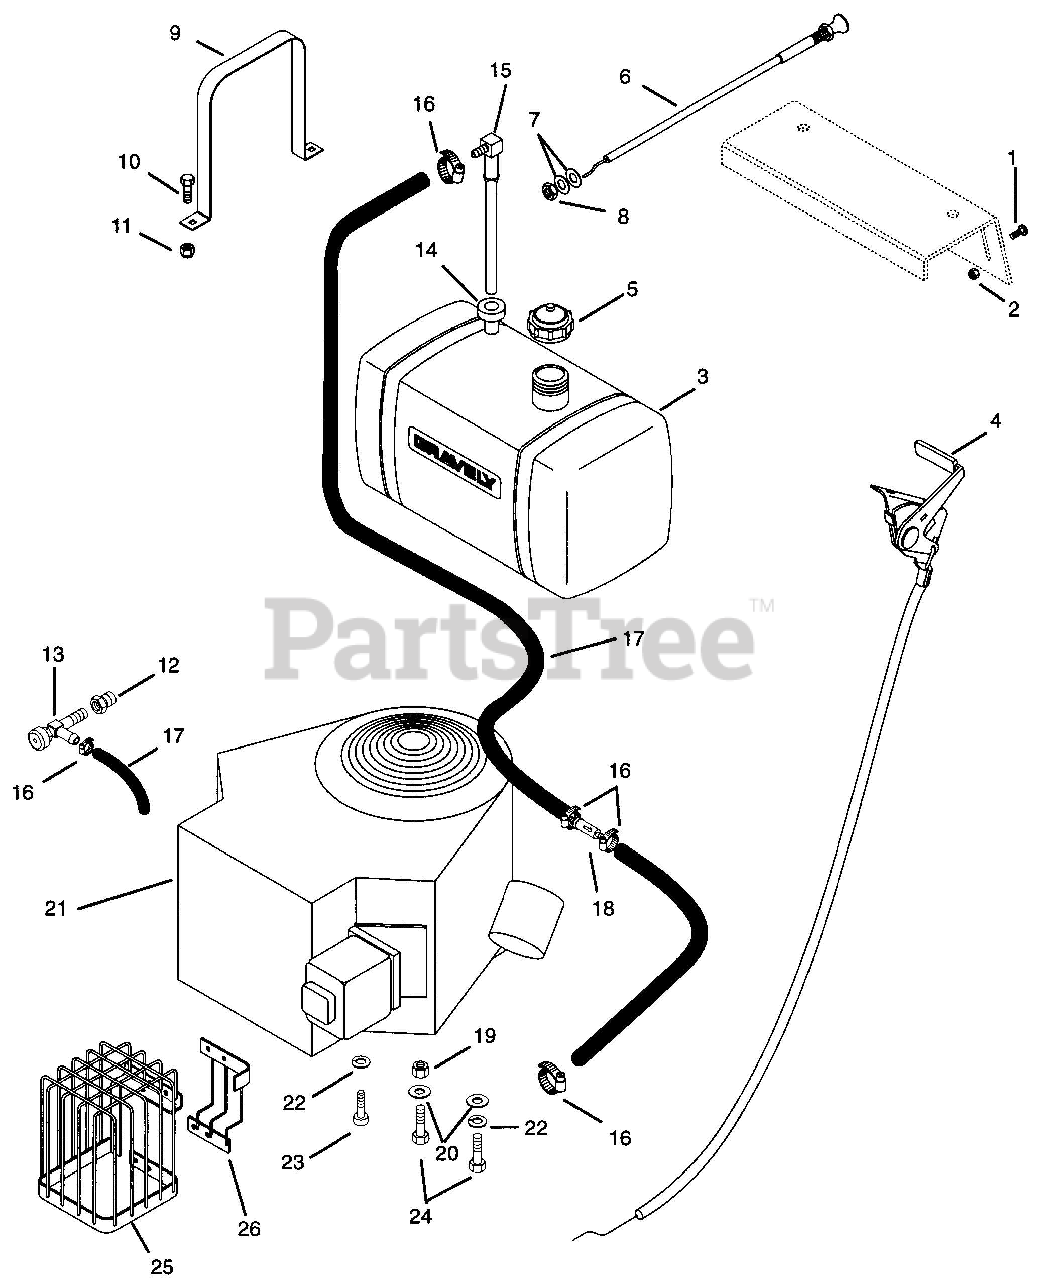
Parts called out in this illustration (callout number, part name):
1	Screw-Machine 10-32 x .50
2	Nut-Locking 10-32 Hex w/ Insert
3	Fuel Tank
4	Assembly - Throttle Control/Cable-B&S
4	Throttle Cable
5	Cap - Fuel Tank
6	Control - Choke
6	Choke for Kohler
7	Washer-Flat-Steel .406 x .812 x .065
8	Nut-Jam .375-24
9	Strap - Fuel Tank
10	Bolt-Hex .25-20 x .63
11	Nut-Locking-Nylon .250-20 Grade 2
12	Adapter - Oil Drain
13	Cock - Oil Drain
14	Bushing
15	Fitting - Tank
16	Hose Clamp
17	Gas Line - Bulk
18	Filter - Fuel
19	Nut-Locking-Nylon .312-18 Grade 2
20	Washer-Flat-Steel .344 x .688 x .065
21	Engine - 16 HP B & S Vanguard
21	Engine - 20 HP Kohler
22	Washer-Lock .313 x .078
23	Screw-Socket Head M8 x 1.25 x 20mm
24	Bolt-Hex M8 x 1.25 x 30mm
25	Weldment - Muffler Guard
26	Weldment - Muffler Guard
